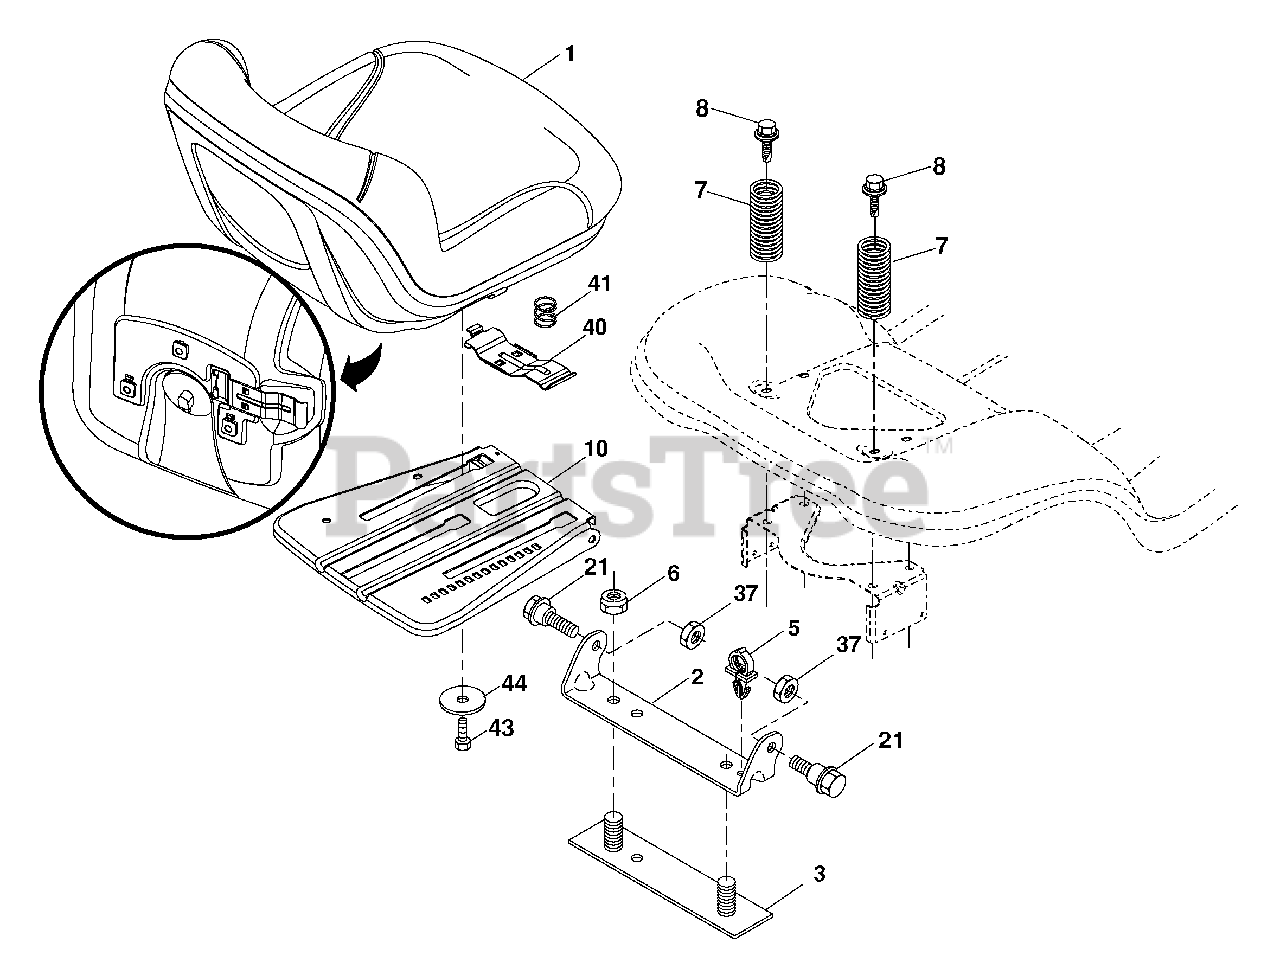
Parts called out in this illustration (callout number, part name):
1	Seat
2	Bracket Pivot Fender
3	Strap, Asm Fender
5	Clip, Push In, Hinged
6	Nut, Lock W/Ins. 3/8-16 unc
7	Spring, Seat Cprsn
8	Bolt 5/16-18 uncx 3/4 w/Sems
10	Pan, Seat
21	Bolt, Shoulder 5/16-18
37	Nut, Lock 5/16-18 unc
40	Handle Slide Seat
41	Spring Latch Seat
43	Bolt Fin Hex 3/8-16 unc x 3/4
44	Washer 13/32 x 2-3/8 x 12 Ga.
